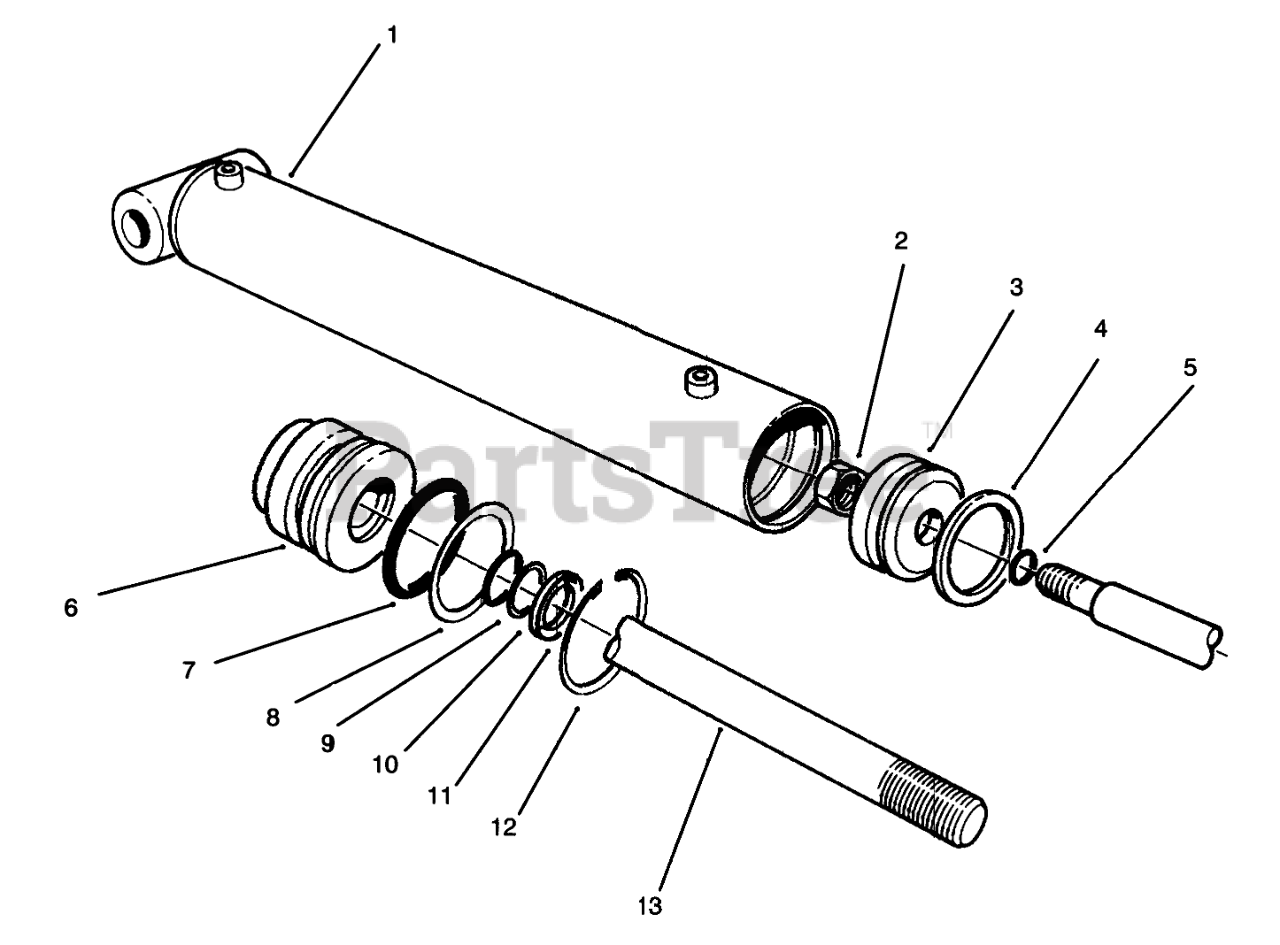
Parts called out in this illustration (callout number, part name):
1	Barrel
2	LOCKNUT
3	PISTON
5	"O"Ring
7	"O"Ring
9	"O"Ring
12	RING-RETAINING
13	SHAFT
